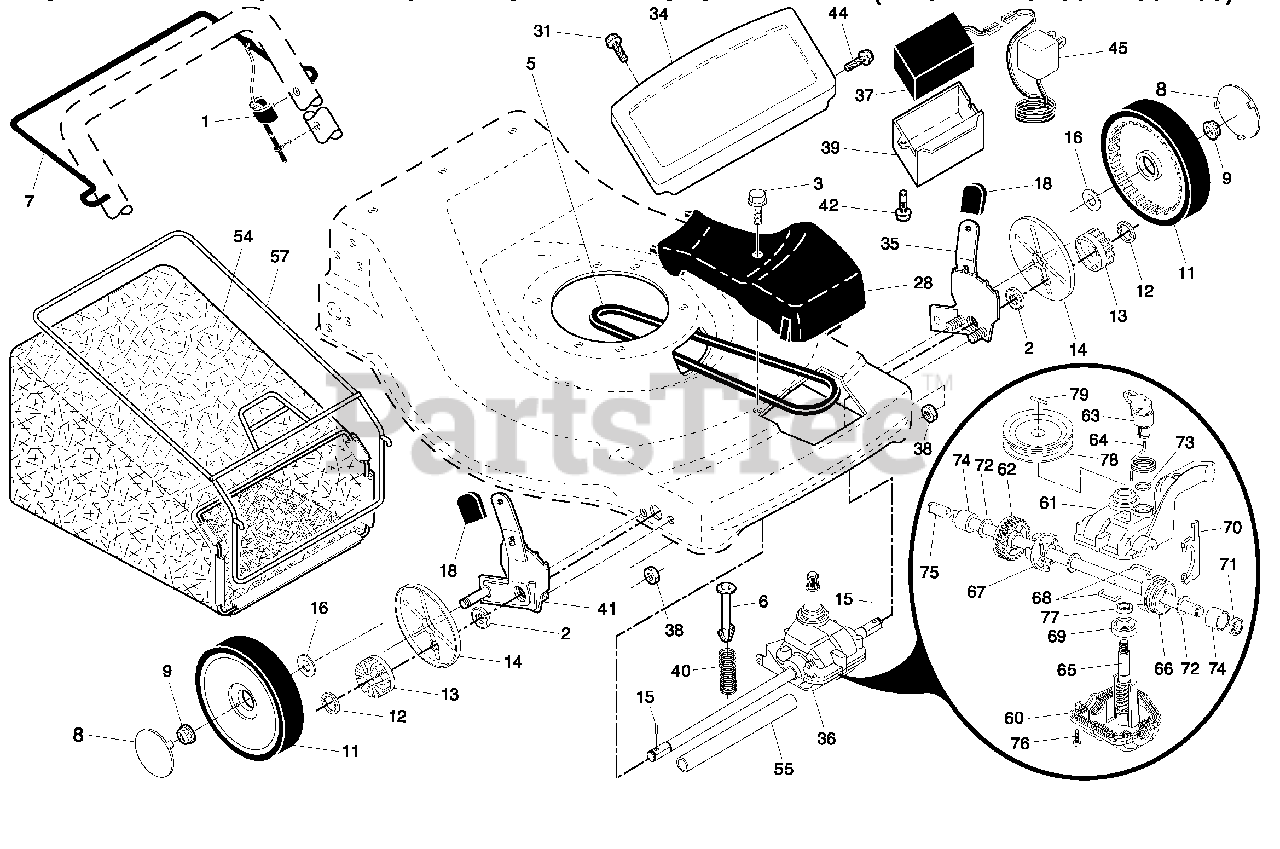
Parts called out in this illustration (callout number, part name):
1	Drive Control Assembly
2	Bearing, Wheel Adjuster
3	Pan Head Tapping Screw #10-24 x 2-3/4
6	Retainer, Spring
7	Bar, Drive Control
8	Hubcap
9	Locknut, Hex
11	Wheel & Tire Assembly, Front
12	E-Ring
13	Pinion
14	Dust Cover
15	Pawl, Drive
16	Washer, Flat 3/8
18	Selector Knob
28	Drive Cover
31	Screw, Trimplate
34	Trimplate
35	Kit, Wheel Adjuster, LH
36	Gear Case Assembly, Complete
37	Battery
38	Locknut 1/4-20
39	Battery Box
40	Spring
41	Kit, Wheel Adjuster, RH
42	Screw, Battery Box
44	Screw, Trimplate
45	Charger, Battery
54	Grassbag Assembly
55	Driveshaft Cover
57	Frame, Grassbag
60	Case, Lower
61	Case, Upper
62	Gear, 27 Teeth
63	Lever, Clutch
64	Spring, Return
65	Shaft, Input
66	Dog, Movable
67	Dog, Fixed
68	Wire, Formed
69	Bearing, Ball
70	Fork, Shift
71	Seal, Output Shaft
72	Washer
73	Seal, Case
74	Bushing
75	Shaft, Output
76	Screw
77	Seal, Input Shaft
78	Pulley, Drive
79	Pin, Retainer
